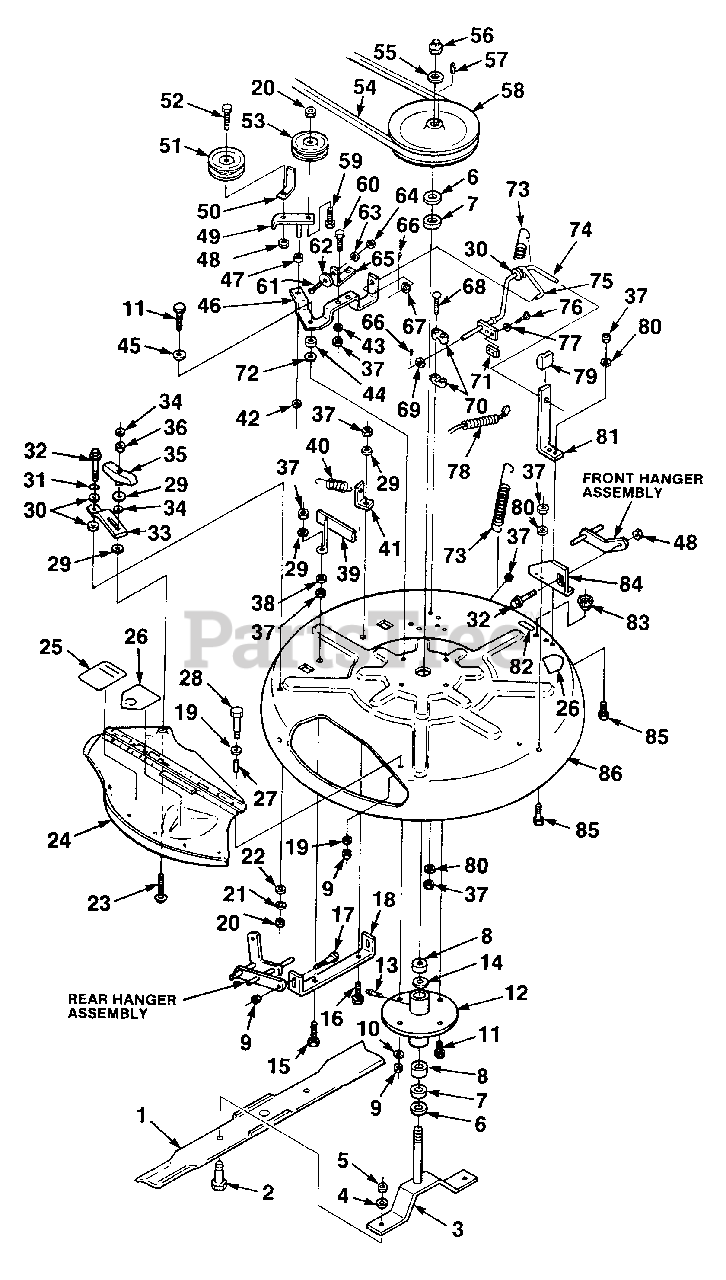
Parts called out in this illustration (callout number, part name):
1	BLADE- Hi- Lift
2	SCREW- Hex centerlock 1/2-13 x 1.25
3	SPINDLE & ADAPTOR
4	WASHER- Lock 1/2
5	NUT- Hex centerlock 1/2-13
7	WASHER- Flat
9	NUT- Hex centerlock 5/16-18
10	WASHER- Lock 5/16"
11	SCREW- Hex centerlock 5/16-18 x 1.5
12	SPINDLE HOUSING
13	FITTING- Lubrication
14	SPACER- Bearing
15	SCREW-Hex centerlock 1/4-20 x 1.250
16	SCREW- Hex centerlock 1/4-20 x.875
17	BOLT- Shoulder 5/16-1 8
18	BRACKET- Rear lift
19	WASHER- Plain 5/16"
20	NUT- Hex centerlock 3/8-16
21	WASHER- Lock 3/8
22	WASHER- Plain 3/8"
23	BOLT-Carriage 1/4-20 x 1.25
24	PLATE & COVER
25	DECAL- Door
26	DECAL-CPSC
28	SCREW- Hex centerlock 5/16-18 x .625
29	WASHER- Plain 1/4"
30	WASHER- Plain
31	WASHER- Spring
32	BOLT- Shoulder 3/8-16 x 1.12
33	ARM- Pivot
34	WASHER- Speed
35	KNOB- Handle
36	NUT- Hex 1/4-20
37	NUT- Hex centerlock 1/4-20
38	WASHER- Flat 5/16"
39	BELT GUIDE
40	SPRING- Extension
41	BRACKET- Damper
42	RING- Retainer
43	WASHER- Plain 1/4"
45	WASHER- Engine
46	BRAKE/CLUTCH LEVER
48	NUT- Hex centerlock 3/8-16
49	IDLER- Pivot
50	GUIDE- Belt
51	PULLEY- Idler
52	SCREW- Hex centerlock 3/8-16 x 1.75
53	PULLEY- Idler
54	MOWER BELT
56	NUT- Hex lock
57	KEY- 3/16 x 1
59	BOLT- Carriage 3/8-16 x 1.75
60	SCREW- Hex centerlock 1/4-20 x 3/4"
61	SCREW- Truss hd. 10-24 x 5"
62	PAD- Brake
63	WASHER- Plain #10
64	NUT- Hex centerlock #10-24
65	BRACKET- Brake pad
66	PIN- Cotter
67	WASHER- Plain 3/8
68	BOLT- Carriage 1/4-20 x 1 1/2
69	WASHER- Plain
71	SWITCH- Deck
72	WASHER- Plain 1/2"
73	SPRING- Extension
74	LEVER- P.T.O.
75	ROD- Link
76	SCREW- Hex slotted #10-16 x.75
77	WASHER- Lock #10
78	COVER- Cable
79	KNOB
80	WASHER- Lock 1/4
81	BRACKET- Brake
82	DECAL- No-Step
83	FITTING- Washout
84	BRACKET- Front lift
85	SCREW- Hex centerlock 1/4-20 x.625
